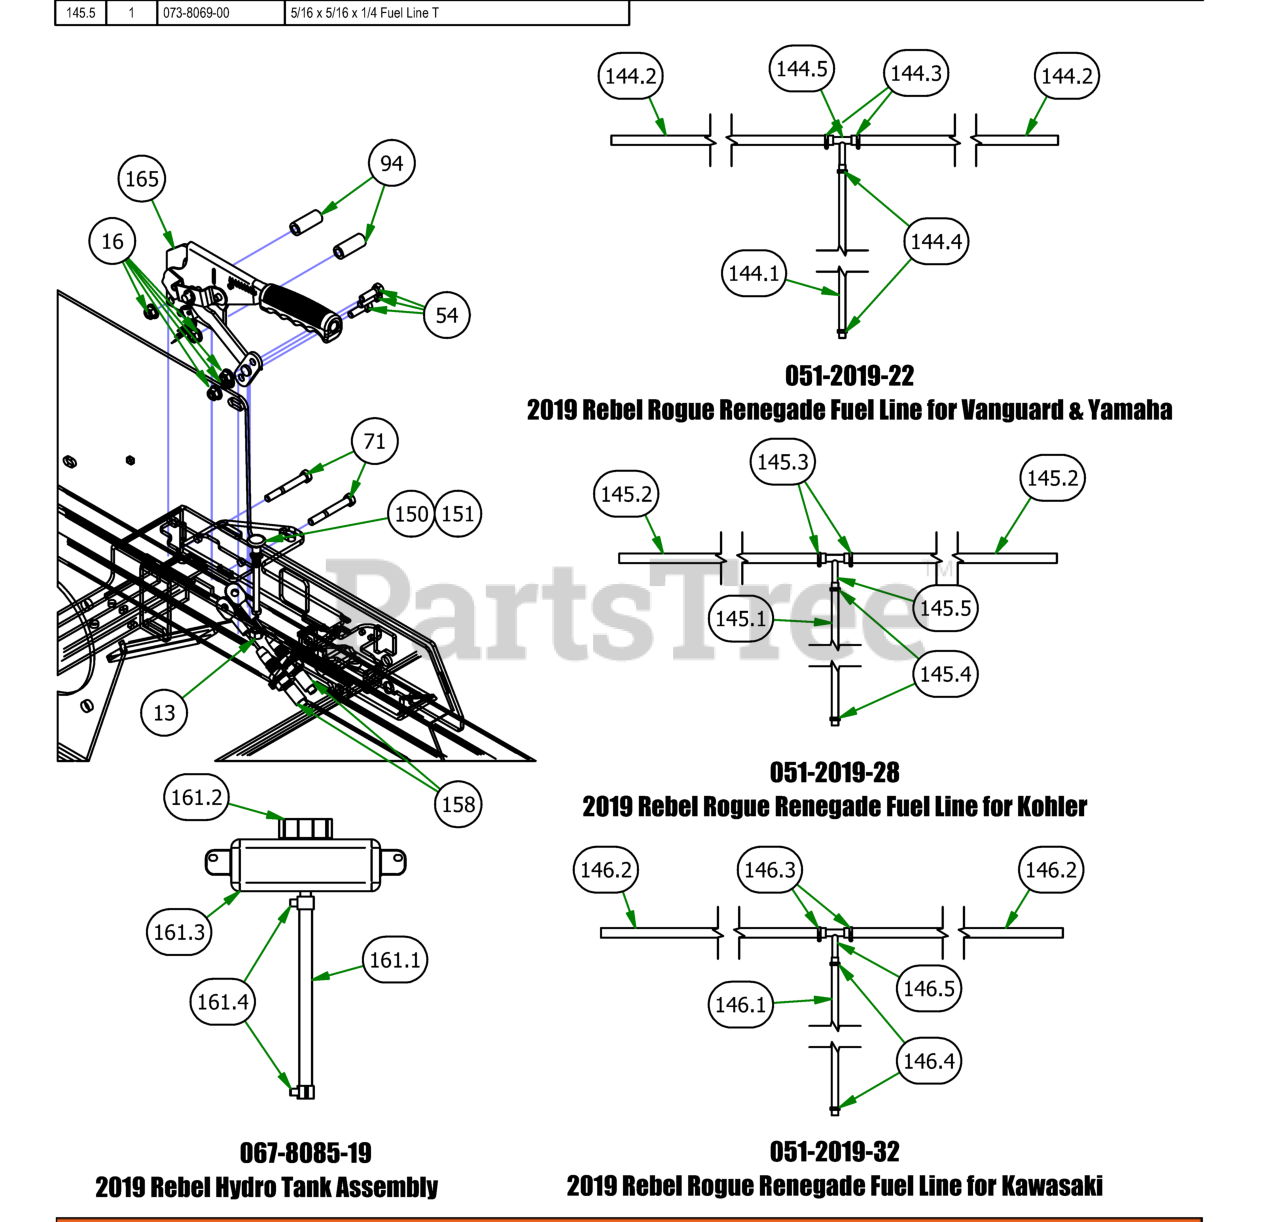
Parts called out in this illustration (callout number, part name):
13	3/8" Fine Threaded Jam Nut
16	5/16" Nylon Flange Nut
54	5/16" x 1" Bolt
71	5/16" x 2 1/2" Bolt
94	2019 Outlaw Brake Handle Spacer .625 x 1.5
144.1	1/4" Fuel Line Hose
144.2	5/16" fuel line hose
144.3	5/16 Fuel Line Clamp
144.4	1/4 Fuel Hose Clamp
144.5	5/16 x 5/16 x 1/4 Fuel Line T
145.1	1/4" Fuel Line Hose
145.2	5/16" fuel line hose
145.3	5/16 Fuel Line Clamp
145.4	1/4 Fuel Hose Clamp
145.5	5/16 x 5/16 x 1/4 Fuel Line T
146.1	1/4" Fuel Line Hose
146.2	5/16" fuel line hose
146.3	5/16 Fuel Line Clamp
146.4	1/4 Fuel Hose Clamp
146.5	5/16 x 5/16 x 1/4 Fuel Line T
151	Choke for 36Hp Vanguard & FX1000 Kawasaki
158	Long Brake Cable
161.1	5/8 Braided Hose
161.2	Hydraulic Tank Cap
161.3	Expansion Tank Outlaw
161.4	5/8 Wire Clamp-Outlaw Only
165	2019 Brake Handle Assembly
